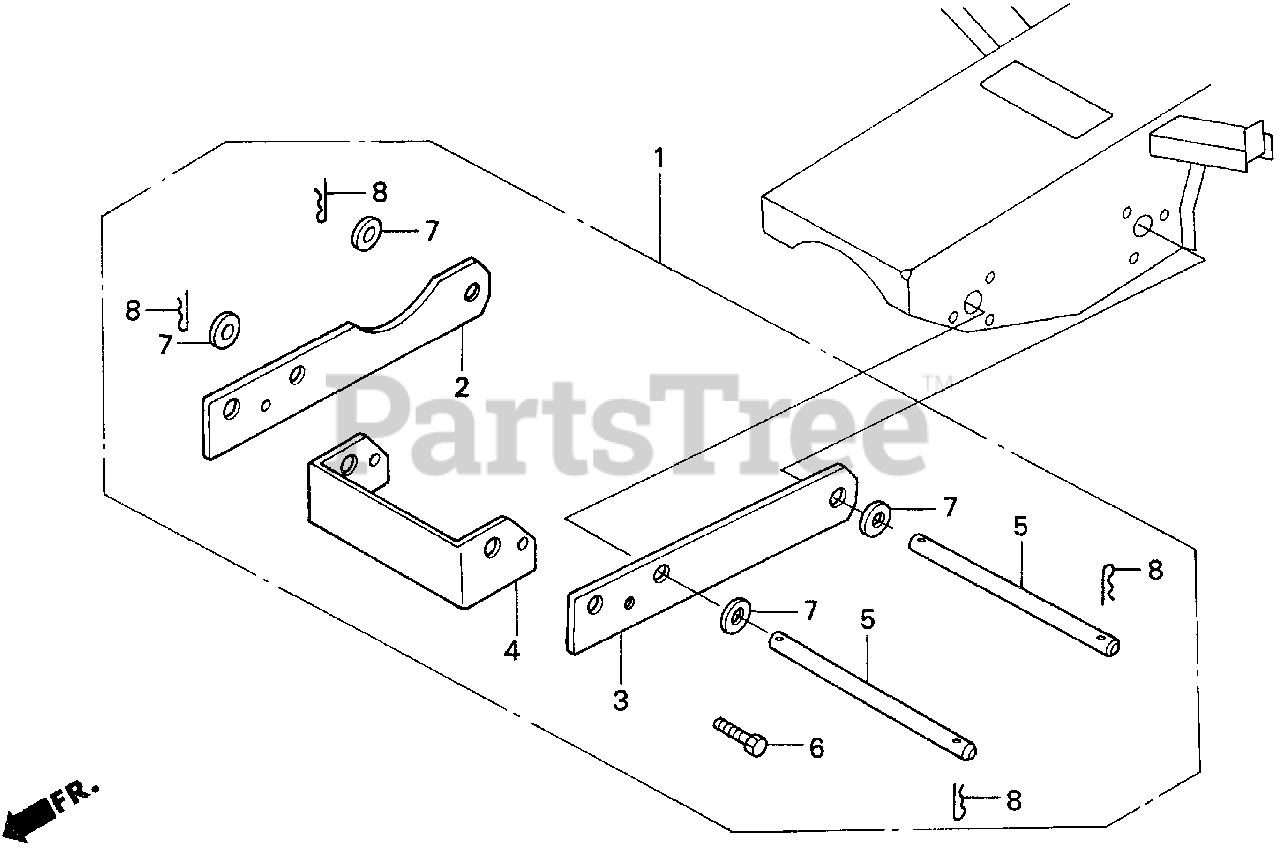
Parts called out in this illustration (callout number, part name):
1	ADAPTER KIT, COUNTERWEIGHT (NOT AVAILABLE)
2	BRACKET, R. FR. END ADAPTER
3	BRACKET, L. FR. END ADAPTER
4	BRACKET, FR. SUPPORT
6	BOLT, HEX. (12X40)
7	WASHER, FLAT (7/8")
8	HAIRPIN (4X80)
